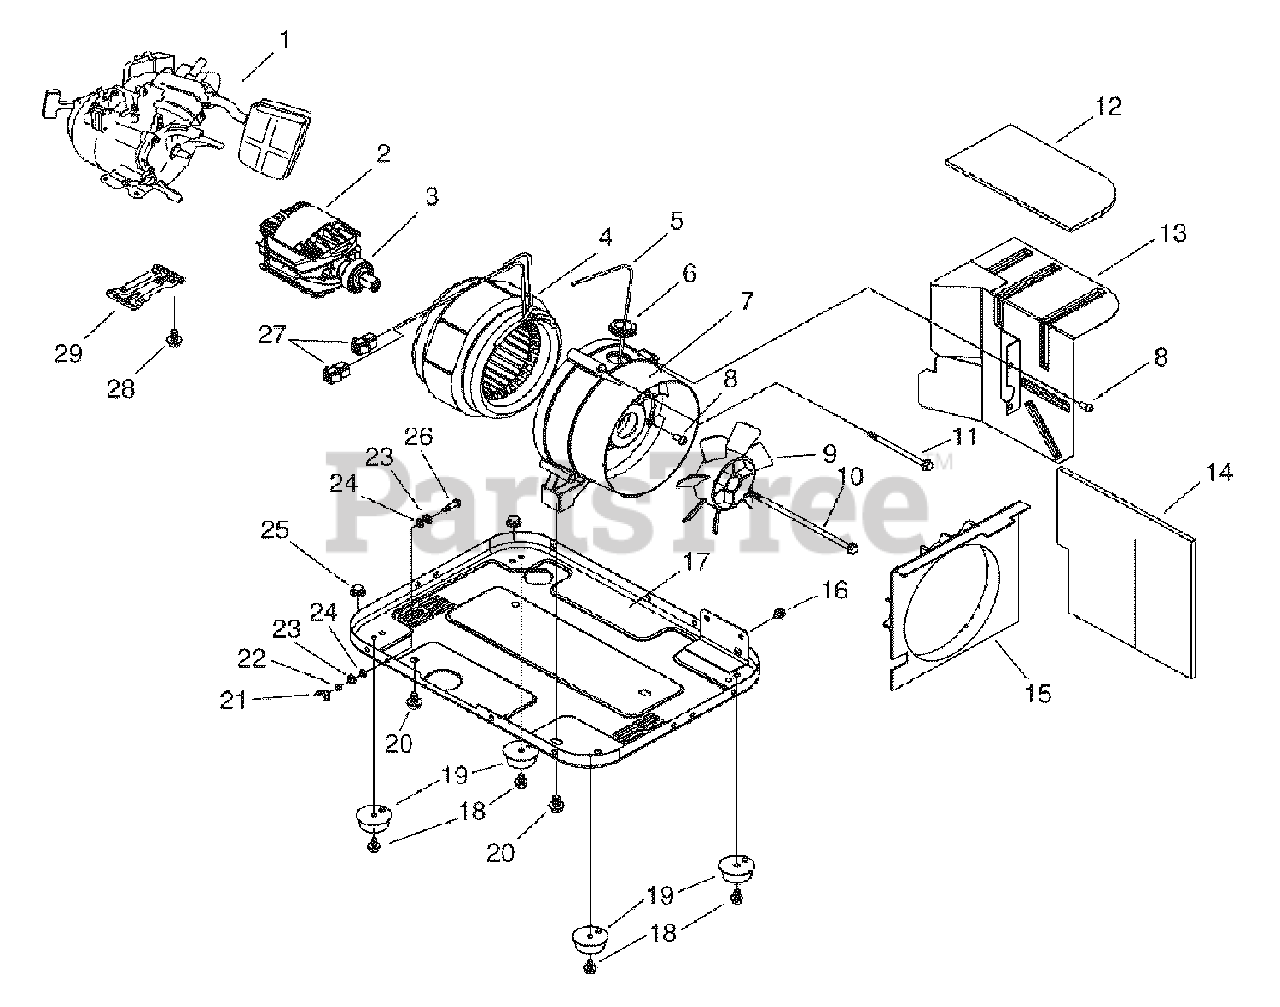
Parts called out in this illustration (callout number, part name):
1	ENGINE, MITSUBISHI, 2.4 HP
5	LEAD, GREEN
6	BUSHING, LEAD WIRE, G790B
8	SCREW, SELF TAP, M6-12
9	FAN, COOLING
10	BOLT, ROTOR
11	BOLT, STATOR
12	INSULATON, HEAT SEALED, #1
13	MFFLR, SEALED
14	INSULATON, HEAT SEALED, #2
15	DUCT, AIR
16	PAN HEAD MACHINE SCREW, M6-1.0, W/L/FW
17	BASE, GENERATOR
18	BOLT, FLANGE, M6-1.0 X 10
19	MOUNT, VIBRATION
20	HEX HEAD CAP SCREW, FLANGE, M8-1.25 X 12
21	NUT, WING, M5 X 0.8
22	NUT, M5 X 0.8
23	WASHER, LOCK
24	WASHER, FLAT
25	NUT, MT-1.25, FLANGE
26	PAN HEAD MACHINE SCREW, M5-0.8 X 20
27	CONNECTOR
28	HEX HEAD CAP SCREW, FLANGE
29	STAND, ENGINE
